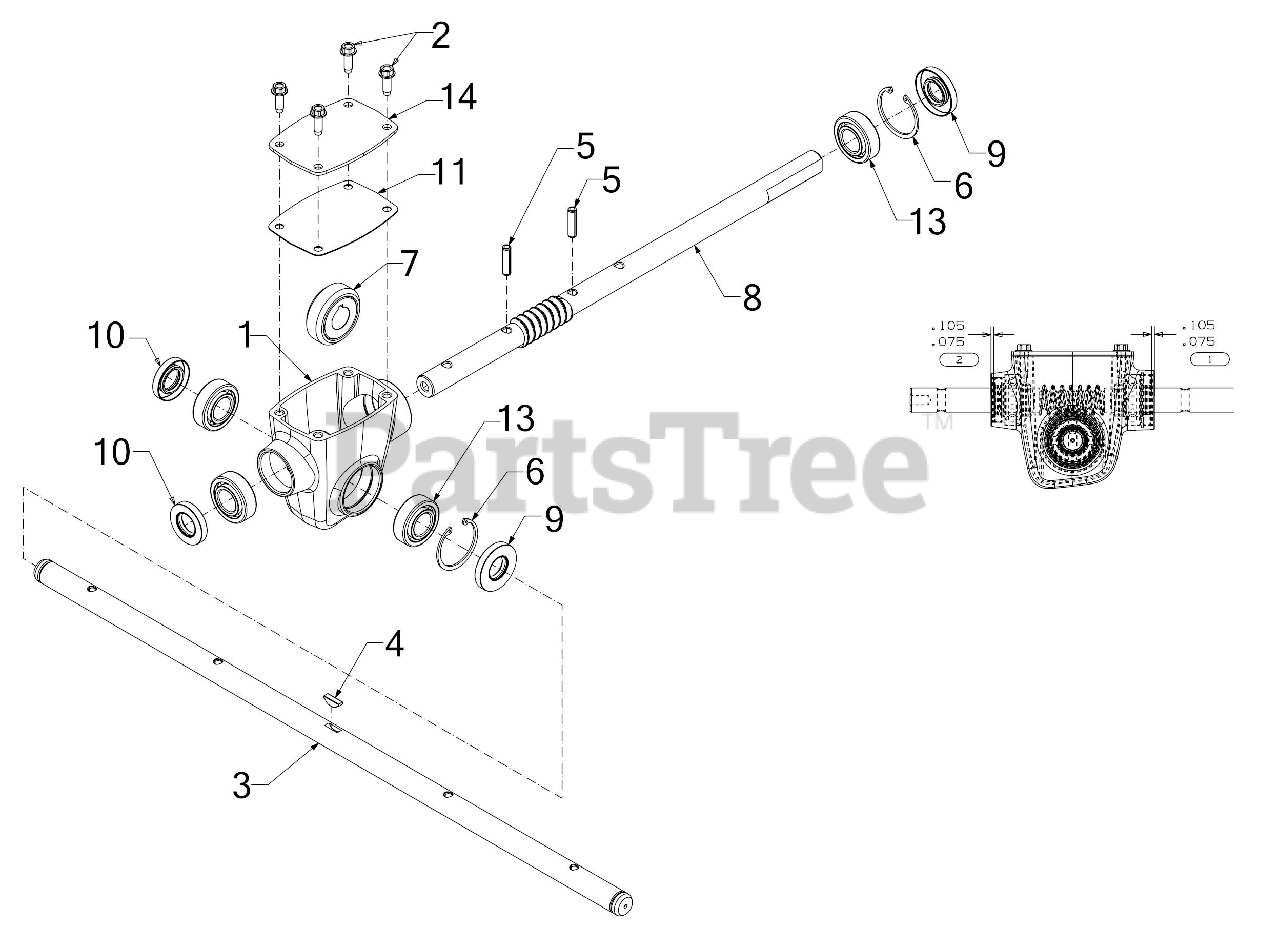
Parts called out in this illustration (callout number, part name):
1	AUGER GEARBOX HOUSING
2	SCREW 1/4-20 x .750
3	26" AUGER AXLE
4	KEY 3/16 x 5/8 H
7	WORM GEAR 20T
11	GEARBOX COVER GASKET
13	BALL BEARING
14	GEARBOX COVER
